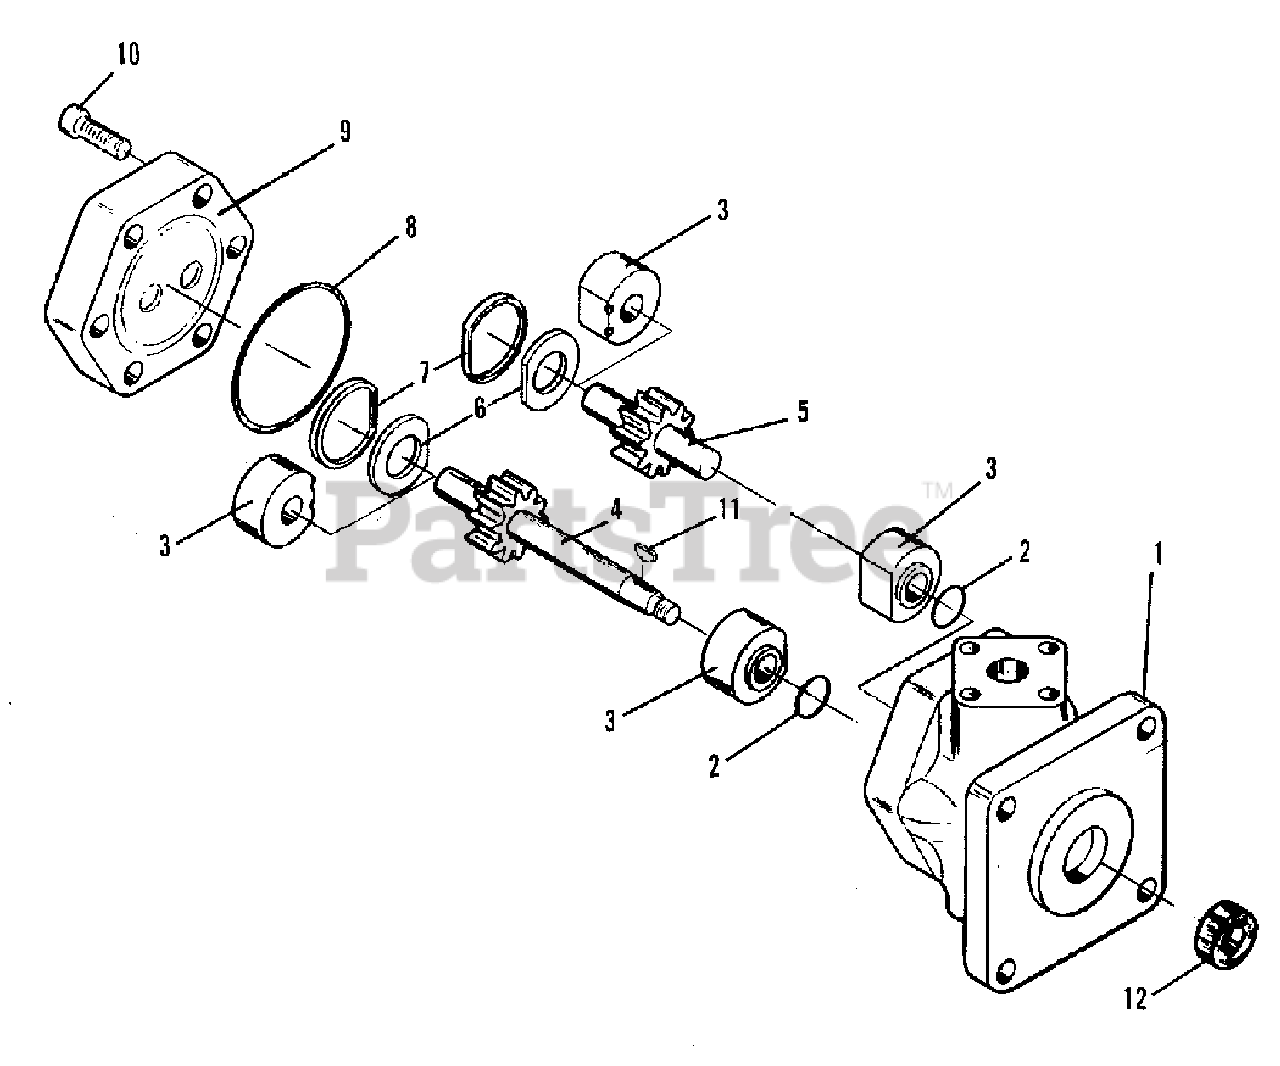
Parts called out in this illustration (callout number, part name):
1	SEAL KIT, hydraulic
2	BODY, (Not serviced; Order 2098141 Complete PUMP ASSEMBLY)
4	BUSHING (Not service; order 2098410 GEAR ASSEMBLY)
5	DRIVE SHAFT & GEAR (Not serviced; order 2098410 GEAR ASSEMBLY)
6	RING, support
7	RING, sealing
10	CAPSCREW, sckt. hd.
12	SEAL, oil
12	GEAR ASSEMBLY (Incl. Items 3, 4, & %)
